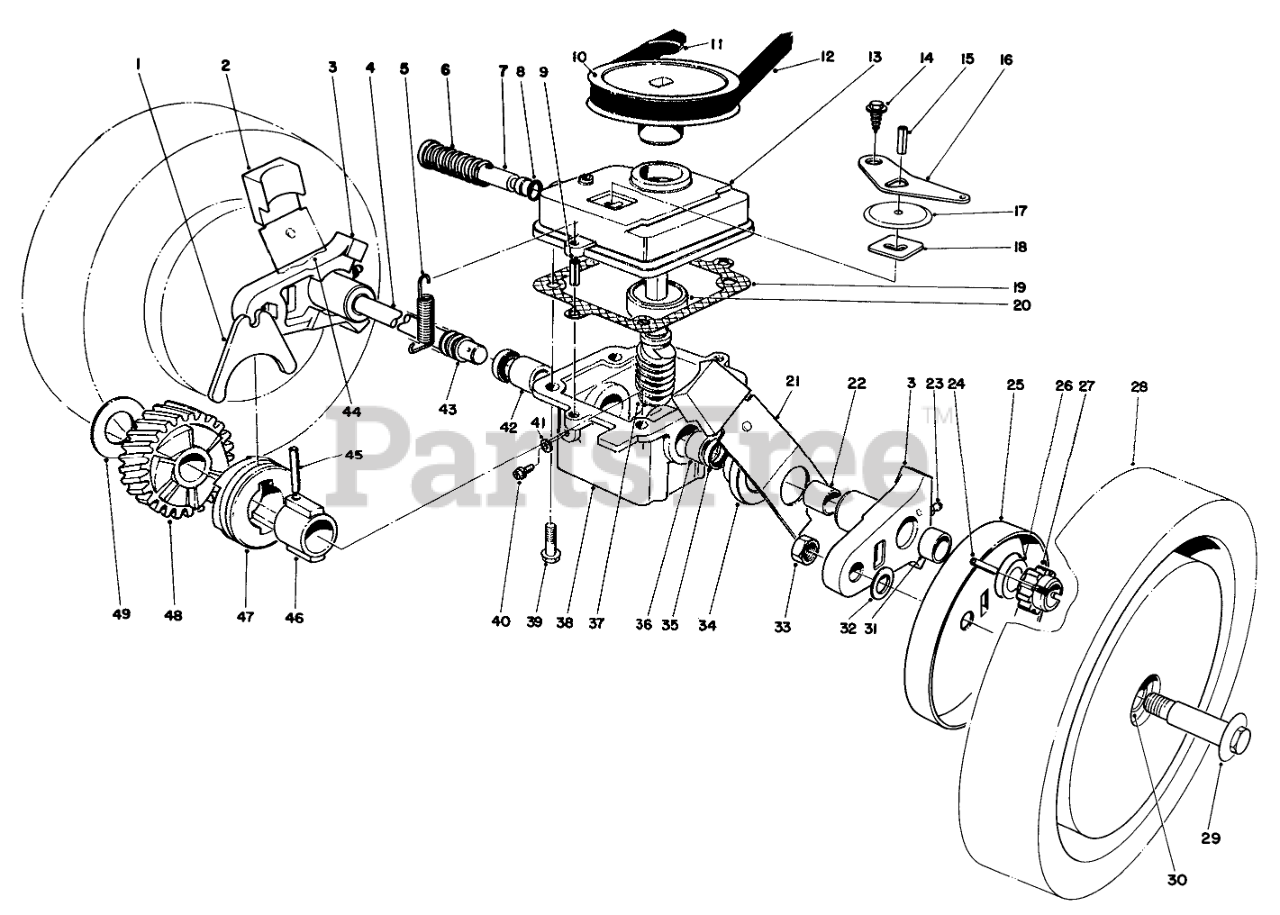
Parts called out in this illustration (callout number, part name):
1	SHIFTER FORK
2	KNOB-ARM
3	Pivot Arm (Incl. Ref. #22, 23831)
4	DRIVE SHAFT (SERVCE)
5	Spring-Tension
6	SPRING
7	SHIFTER ROD
8	O-RING
9	3/16 X 1/2 ROLL PIN
10	PULLEY
11	PUSH-ON 93-3236
12	V BELT
13	Case-Upper
14	Screw
15	PIN-ROLL
16	SHIFTER ARM
17	TRANS DUST COVER
18	LATCH PLATE
19	GASKET
20	Bearing
21	SPRING ARM ASM SP LH
22	BUSHING
23	FITTING-GREASE
24	Pin
25	WHEEL COVER
26	THRUST WASHER
27	PINION GEAR 14T
28	Wheel 8 Tire Assembly (Incl. Ref. #30)
29	BOLT-WHEEL
30	BUSHING
31	BUSHING
32	WASHER
33	Nut
34	End Cap
35	Seal
36	Bushing
37	Worm Shaft 8 Gear (Incl. Ref. #48)
38	Gear Case (Incl. Ref. #35-36&42)
39	Screw
40	NYLON SCREW
41	FILL PLUG GASKET
42	Bushing
43	COVER-SHAFT, DRIVE
44	SPRING ARM ASM SP RH
45	COIL PIN
46	SLEEVE
47	CLUTCH JAW
48	Helical Gear
49	THRUST WASHER
